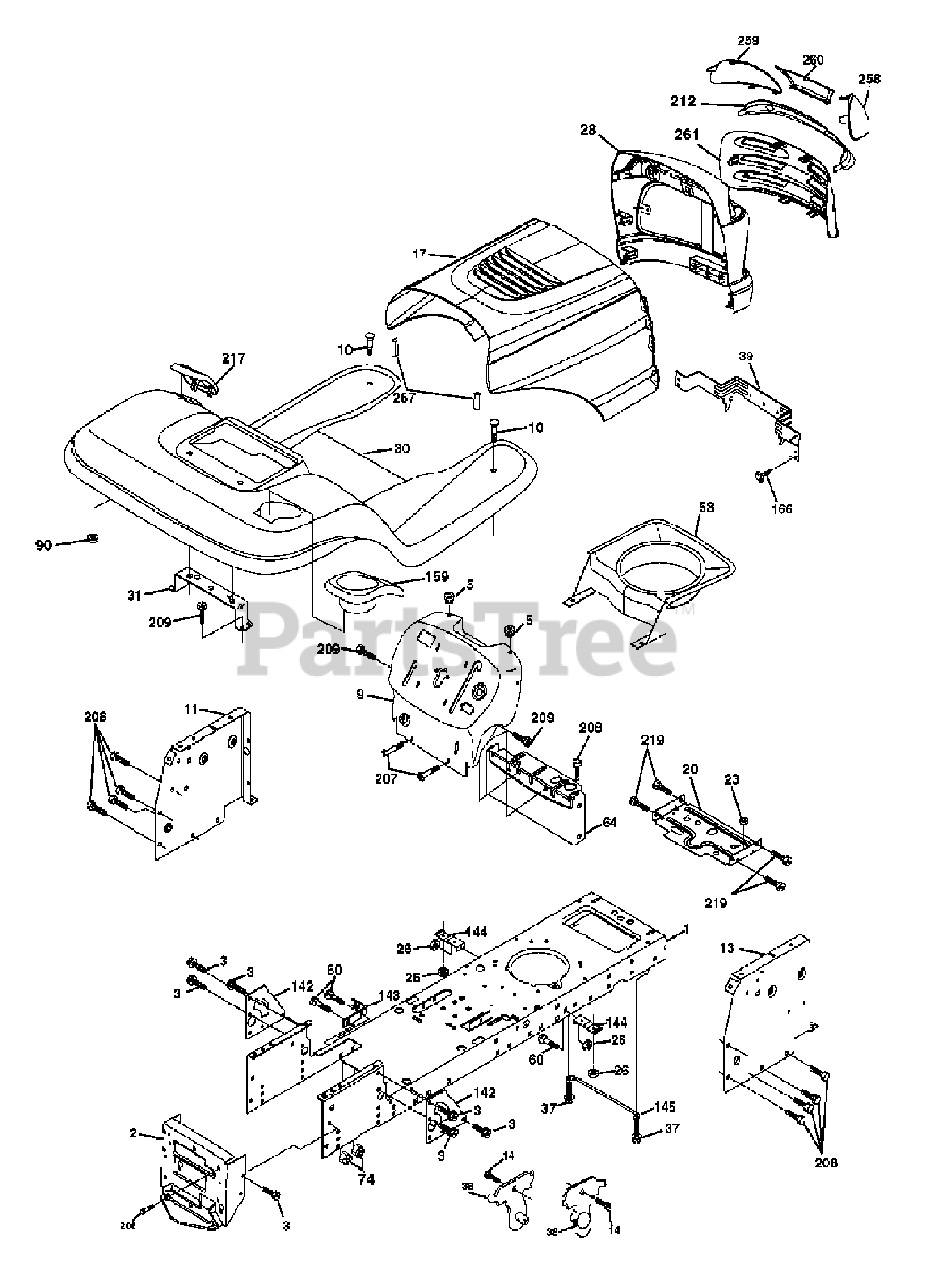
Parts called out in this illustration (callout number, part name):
1	Chassis Stamping
3	Screw 3/8-16 x 3/4
9	Dashboard
10	Bolt Rdhd Sqnk 3/8-16 Unc x 1
11	Panel Dash Lh
13	Panel Dash Rh
14	Screw Thdrol 3/8-16 x 1/2
17	Hood
20	Plate Mtg Battery/Fuel Tank
26	Nut Lock w/Insert 3/8-16 Unc
28	Grille Lens Asm
30	Fender
37	Screw Thdrol 5/16-18 x 1/2
38	Bracket Asm Pivot Mower Rear
39	Bracket Pivot Laser
60	Bolt RDHD SQNK 3/8-16 x 3/4
64	Dash Lower Stlt
74	Nut Crownlock 3/8-16
90	Nut Self-Thd. Wsh-Hd 1/4 Zinc
142	Plate Reinforcement Stlt
143	Bracket Swaybar Chassis
144	Bracket Ft Rest
145	Rod Pivot Chassis Hood
159	Cupholder YTGT Grey
166	Screw Hw Hd Hi-Lo #13-16 x 3/4
206	Bolt Shoulder 5/16-18 TT
207	Screw Thdrol 5/16-18 x 1/2 TYTT
208	Screw Thdrol 3/8-16 x 1/2 Ty-TT
209	Screw Hex Wsh Thdr. 3/8-16 x 3/4 BL
212	Insert Lens Reflect
217	Console Fuel Window STLT
219	Screw 5/16-18 x 3/4 SMGML Tap/BL
257	Bumper Hood Large
258	Lens Husq. Laser LT Clear RH
259	Lens Husq. Laser LT Clear LH
260	Lens Cover Husq. Laser
261	Insert, Grille
